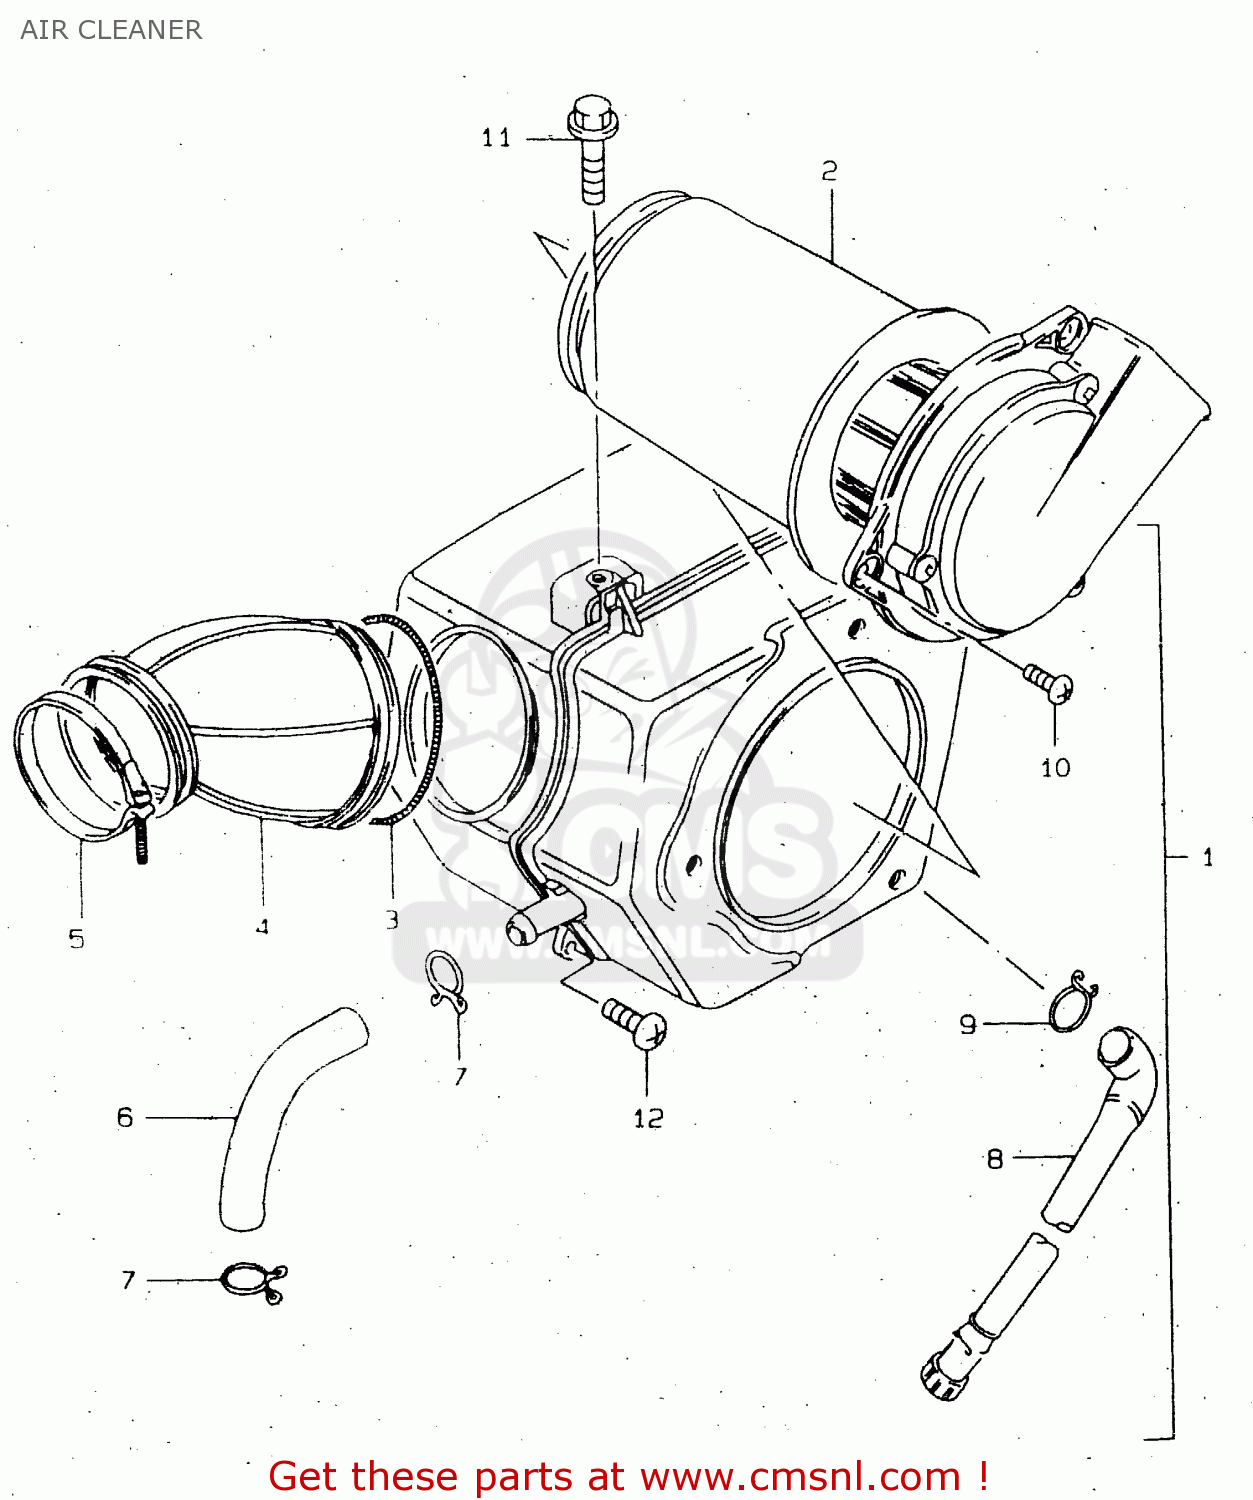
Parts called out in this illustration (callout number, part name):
1	CLEANER ASSY,AIR
2	FILTER
3	CLAMP,AIR CLEANER SIDE
4	TUBE,OUTLET
5	CLAMP
6	TUBE,BREATHER
7	CLIP
8	TUBE,DRAIN
9	CLIP
10	SCREW
11	BOLT
12	SCREW
